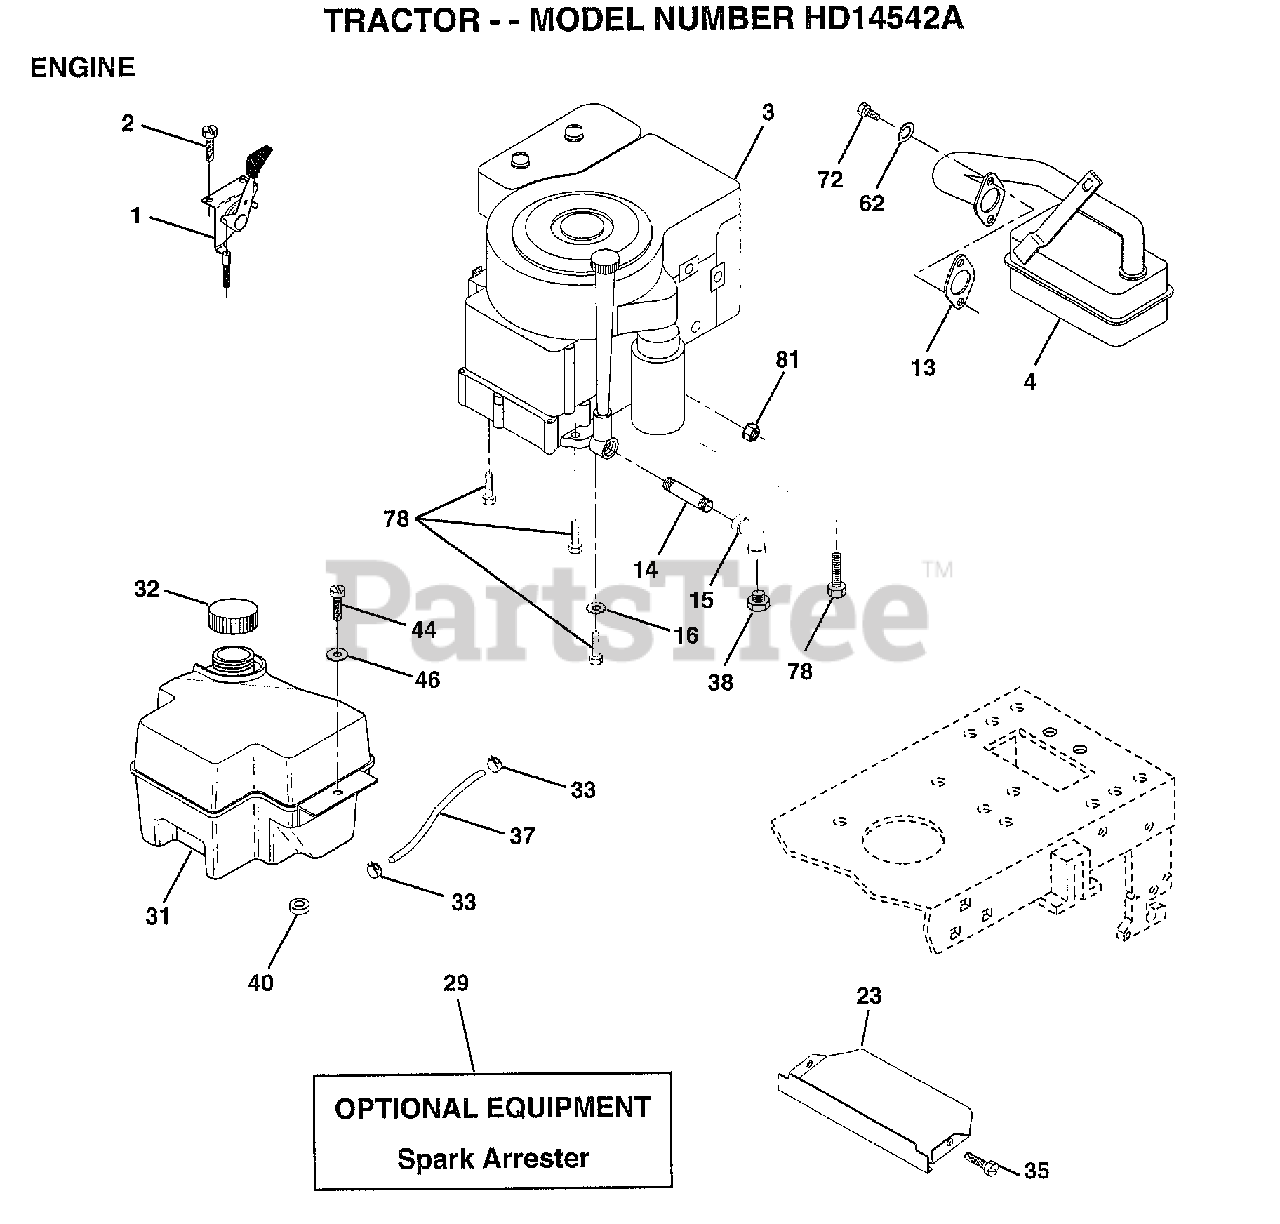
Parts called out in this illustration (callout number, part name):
1	CONTROL THROTTLE
2	SCREW LT
4	MUFFLER
14	PIPE NIPPLE
15	ELBOW
16	LOCKWASHER
23	SHIELD.BRN/DBR.GD
31	TANK.FUEL.FRONT.
32	CAP ASM FUEL
33	HOSE CLAMP
35	SCREW
37	LINE FUEL
44	SCREW HEX CRT
46	WASHER
62	LOCKWASHER
72	SCREW
78	SCREW
81	NUT
